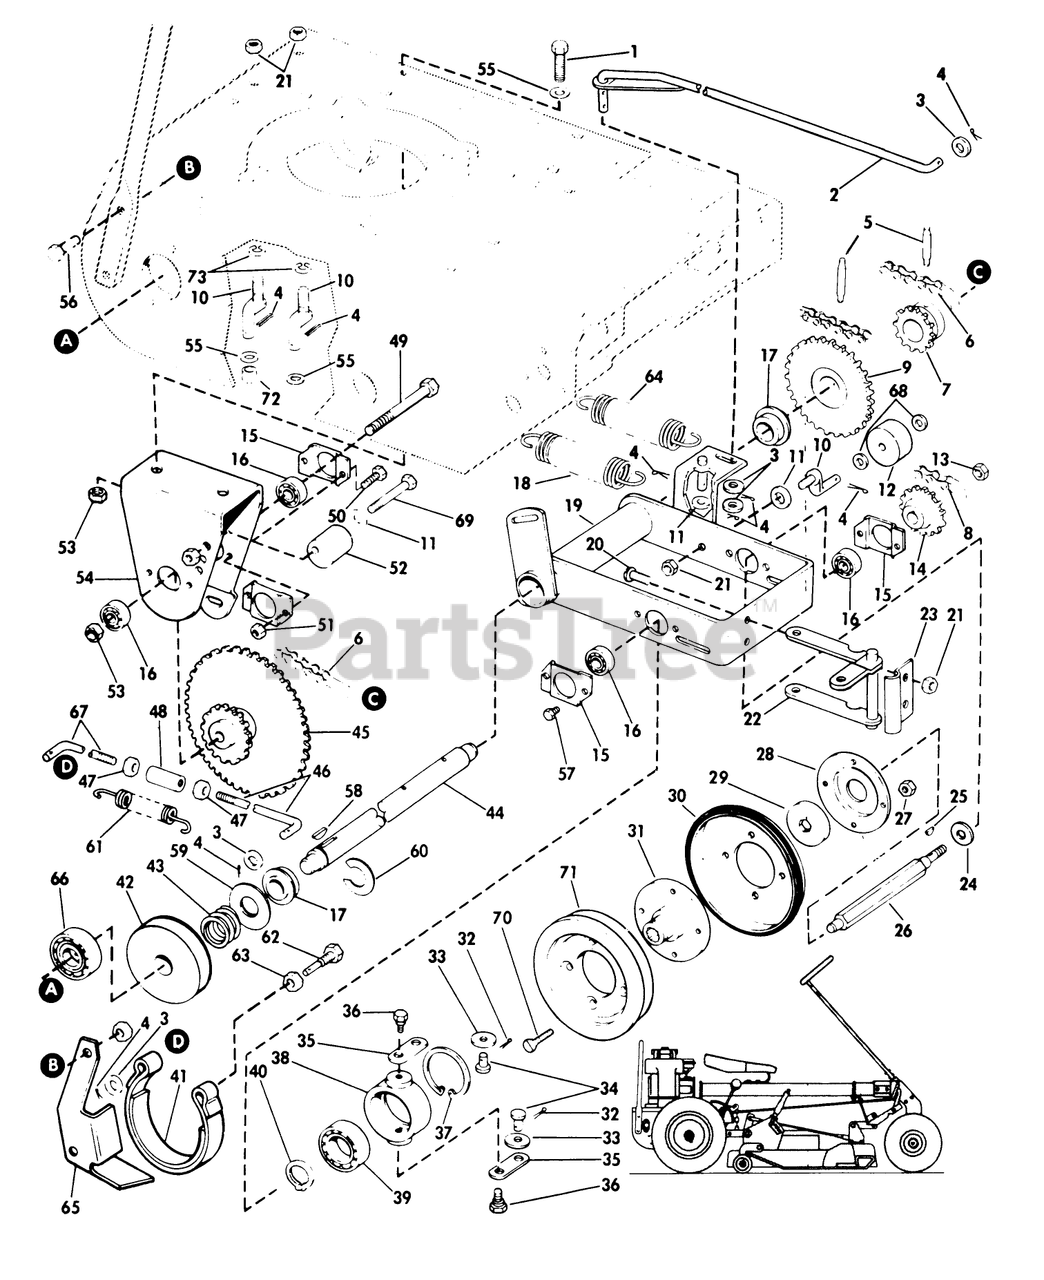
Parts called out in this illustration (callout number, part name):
13	LOCKNUT
47	STOP NUT
53	LOCKNUT
